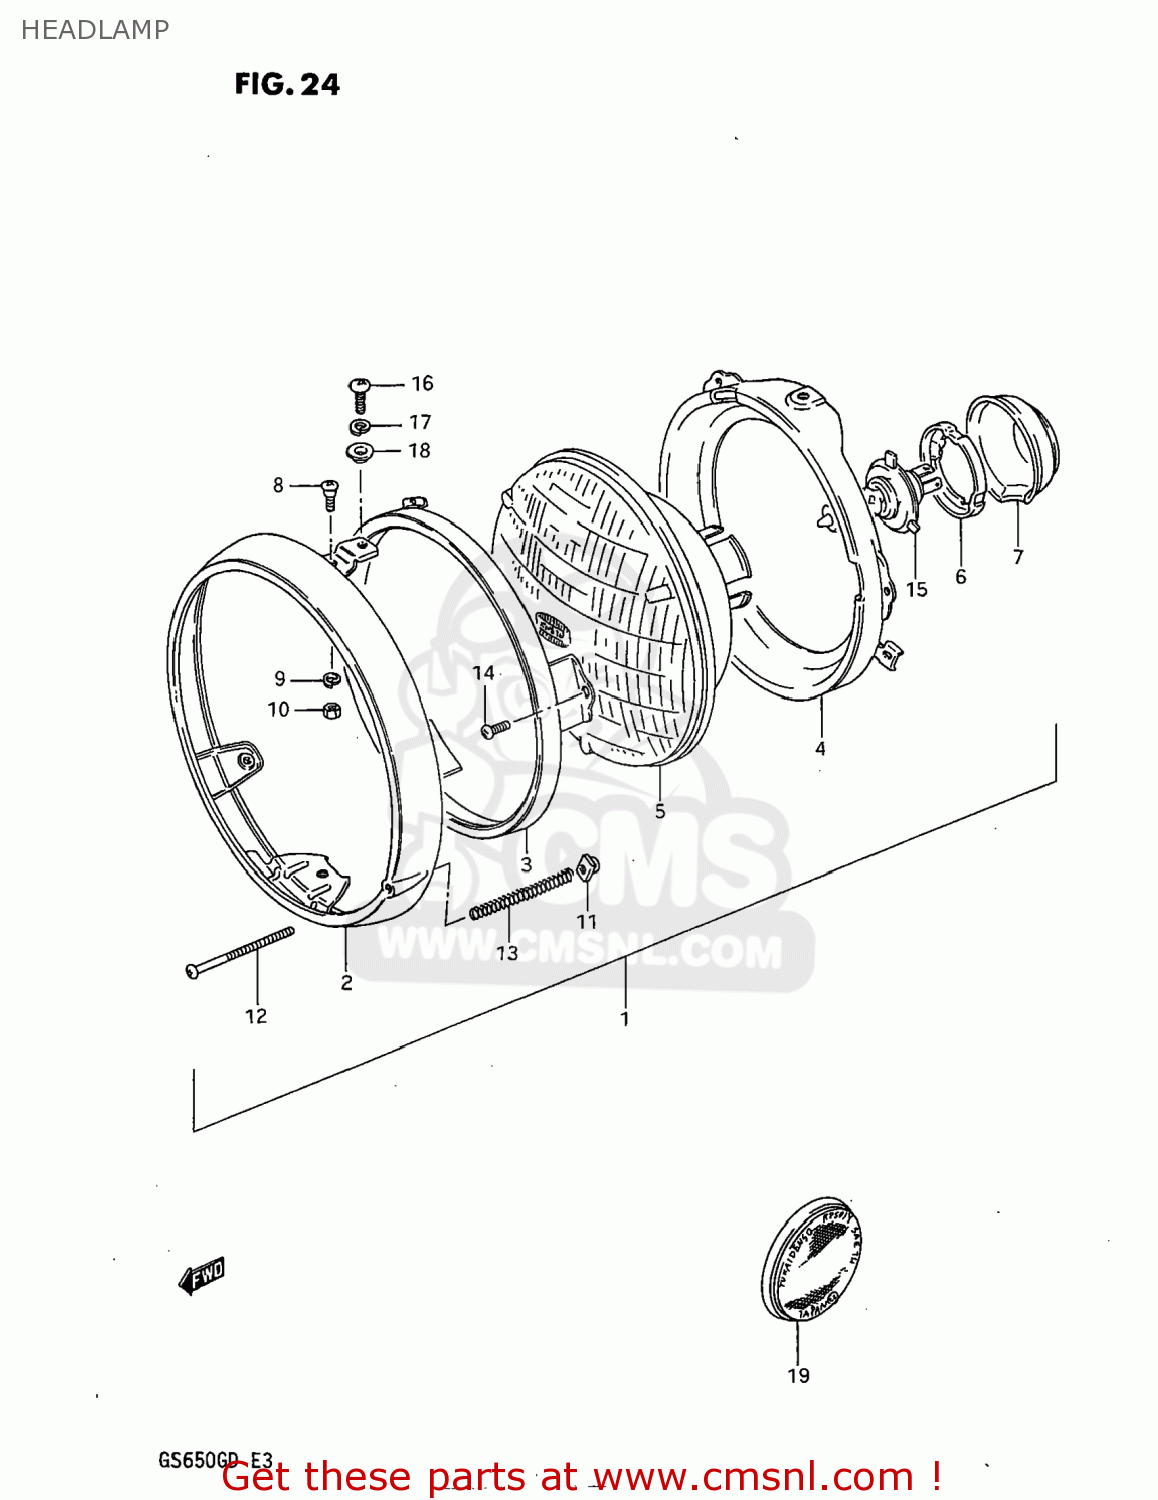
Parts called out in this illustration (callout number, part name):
1	HEADLAMP ASSEMBLY
2	RIM
3	RETAINING RING
4	RING
5	LAMP UNIT
6	SETTING,BULB
7	COVER,HEADLAMP SOCKET
8	H/LAMP LENS UNIT FITING SCRE
9	LOCK WASHER
10	NUT
11	NUT
12	SCREW,HEADLAMP ADJUST
13	SPRING,ADJUSTING
14	SCREW
15	BULB(12V60/55W,H4)
16	SCREW
17	WASHER,LOCK
18	WASHER
19	REFLEX REFLECTOR,RR
